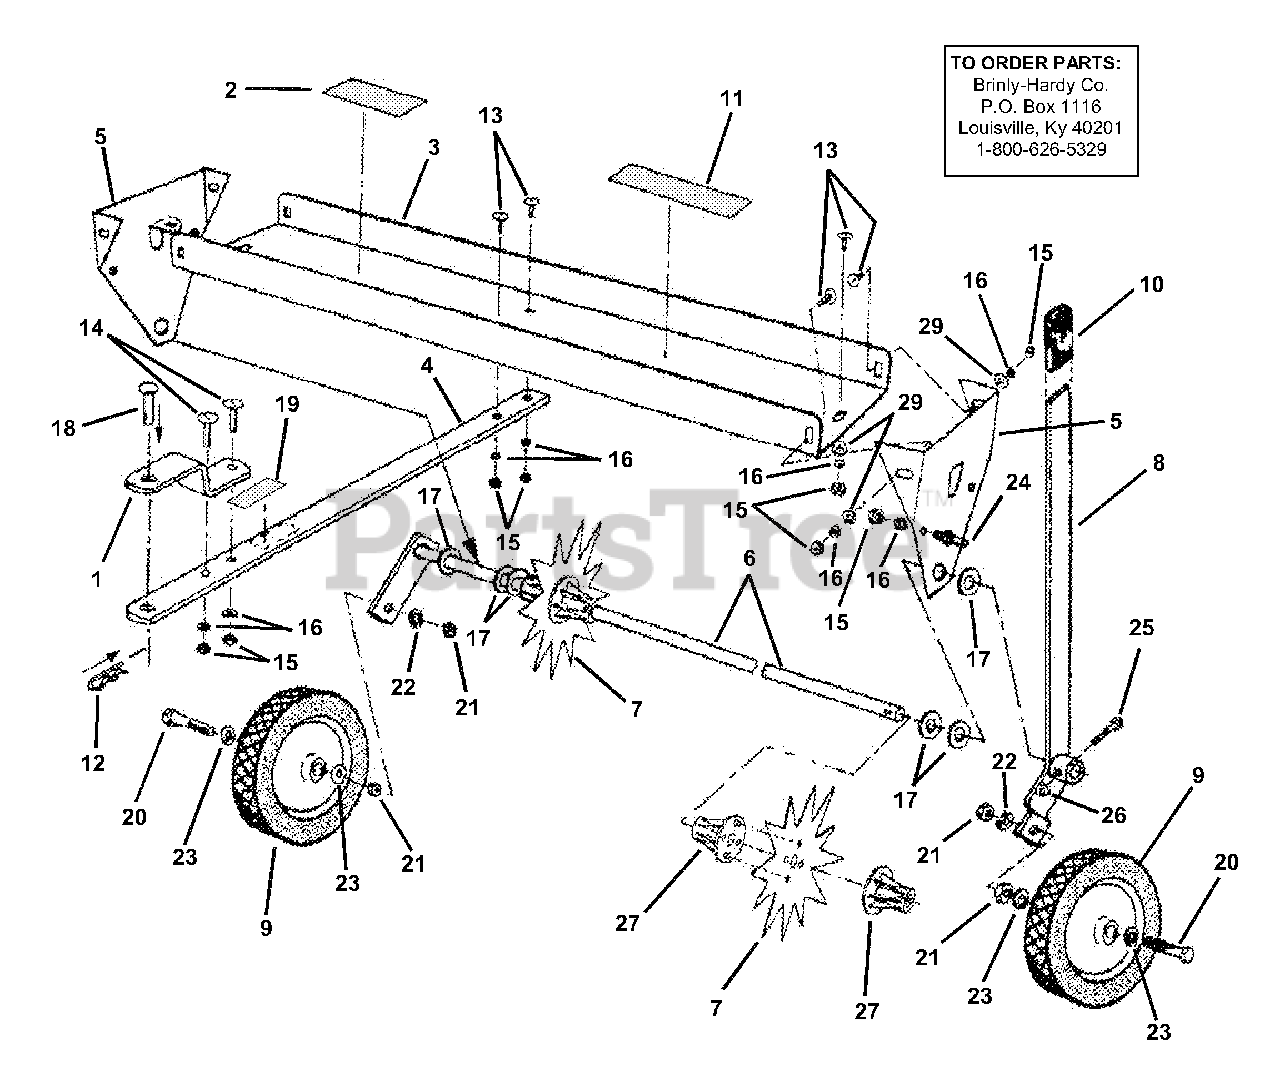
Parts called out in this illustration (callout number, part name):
1	CLEVIS, Drawbar
2	DECAL, Logo
5	PANEL, End
6	ASSEMBLY, Axle
8	ASS'Y, Handle
9	WHEEL
10	GRIP, handle
11	DECAL, Caution
12	HAIRPIN COTTER
13	SCREW, 5/16 x 3/4" Round Head
14	SCREW, 5/16 x 1" Round Head
15	NUT, 5/16" Hex
16	WASHER, 5/16" Lock
17	WASHER, 5/8" (Thick)
18	PIN, 1/2 x 2-1/4" Drawbar
19	DECAL, Caution
20	BOLT, 1/2 x 3" Hex
21	NUT, 1/2" Hex
22	WASHER, 1/2" Lock
23	WASHER, 1/2" Flat
24	PIN, Transport Lock
25	BOLT, 1/4 x 1-1/4" Hex
26	NUT, 1/4" Hex Lock
27	SPACER/BEARING HALF
28	WASHER, 5/8" (Thin)
29	WASHER, 5/16" Flat
